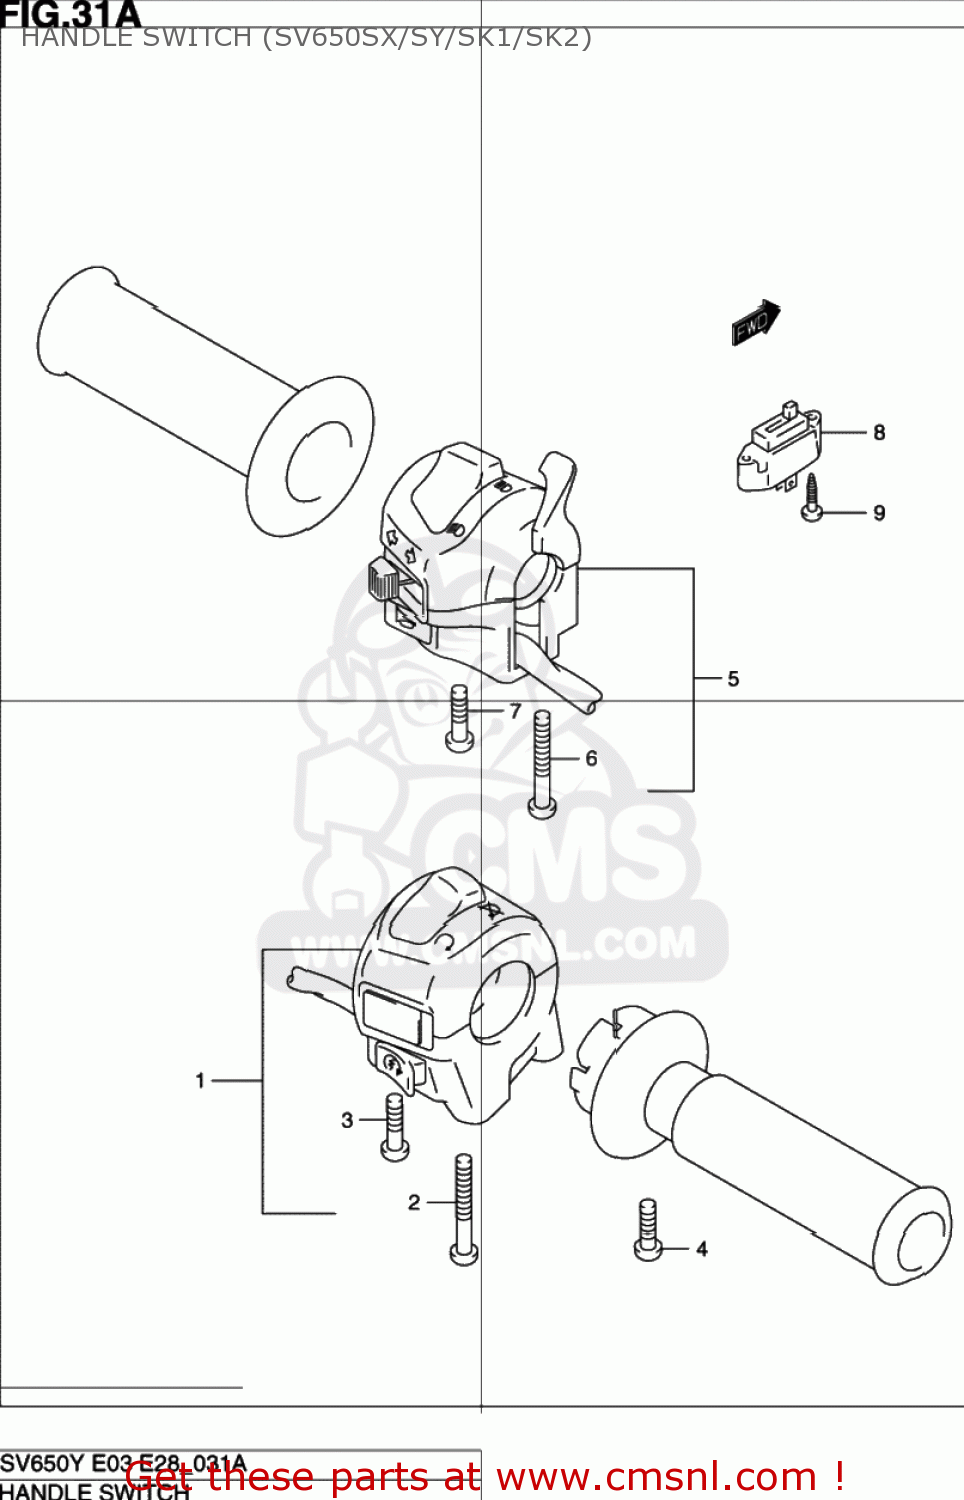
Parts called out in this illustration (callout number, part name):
1	SWITCH ASSY,HANDLE,R
2	SCREW
3	SCREW
4	SCREW
5	SWITCH ASSY,HANDLE,L
6	SCREW, 5X45
7	SCREW(5X25)
8	SWITCH ASSY,CLUTCH
9	SCREW
